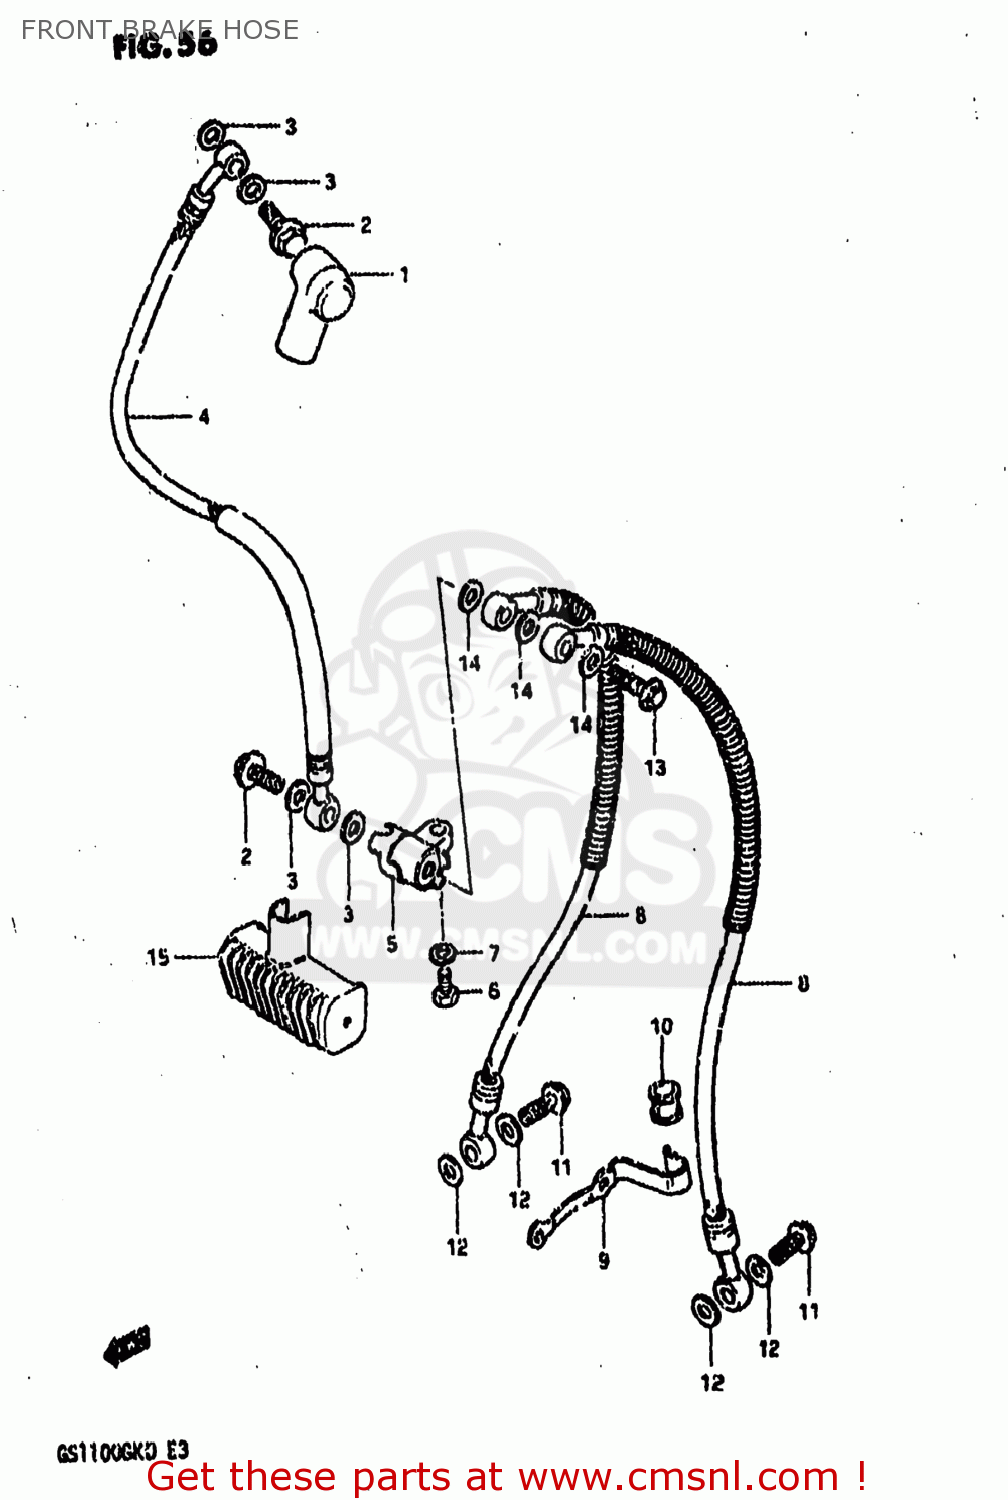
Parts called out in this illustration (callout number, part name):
1	BOOT,MASTER CYLINDER
2	BOLT,UNION
3	WASHER
4	HOSE,FRONT BRAKE
5	JOINT,BRAKE HOSE
6	BOLT
7	LOCK WASHER
8	HOSE,BRAKE
9	GUIDE,BRAKE HOSE NO.2
10	BUSH,BRAKE HOSE GUIDE,NO.2
11	BOLT,UNION
12	WASHER
13	BOLT,UNION
14	WASHER
15	COVER,BRAKE HOSE JOINT
